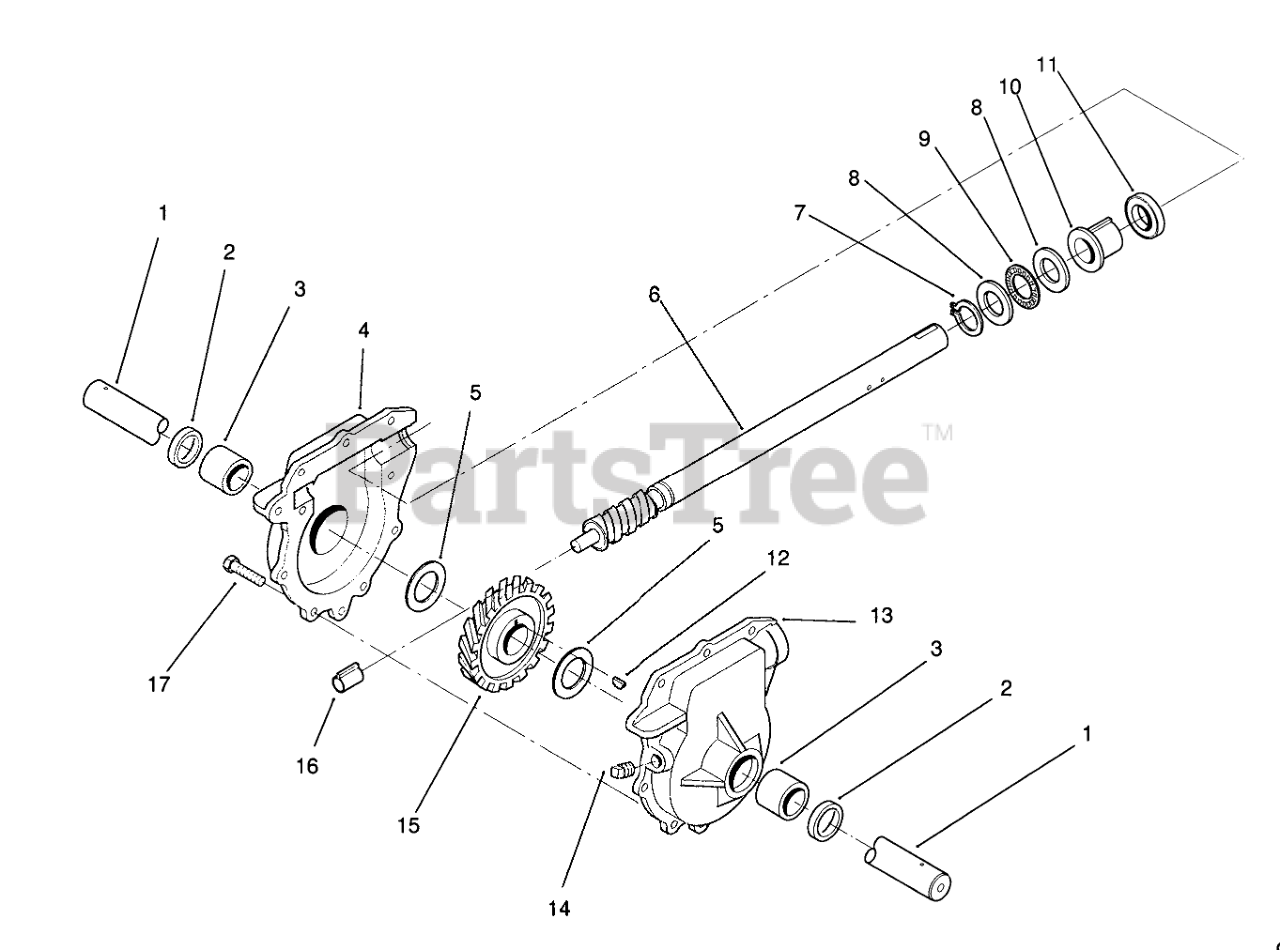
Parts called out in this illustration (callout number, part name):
1	SHAFT-AUGER
2	SEAL-OIL
3	BUSHING
4	Gearcase Assembly-R.H. (Incl. Ref. #2-3)
5	WASHER-THRUST
6	SHAFT-IMPELLER
7	RING-RETAINING, Ext
8	WASHER-THRUST
9	BEARING-THRUST
10	BUSHING-INPUT
11	SEAL-OIL
12	KEY-WOODRUFF
13	Gearcase Assembly-L.H. (Incl. Ref. #2-3)
14	PLUG-PIPE, SQH
15	GEAR-HELICAL
16	BUSHING-WORM
17	SCREW-HWH
